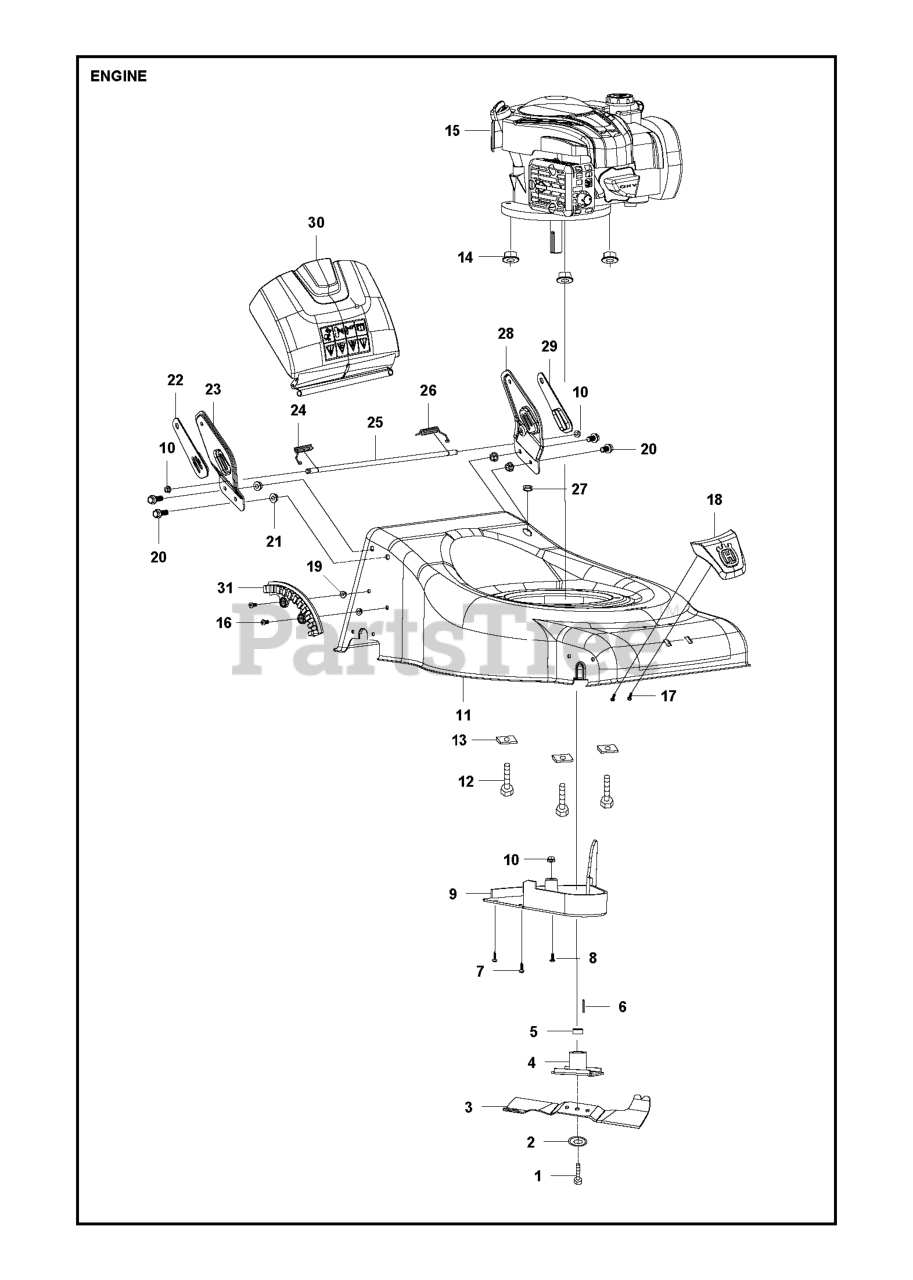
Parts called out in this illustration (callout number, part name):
8	SCREW M6*16 #26800204601
10	LOCK NUT M6,GB/T6187.1-2000 #2
14	LOCKING BOLT M8,GB6187.1 #2680
20	BOLT M8*16 #26800606401
22	PLATE RIGHT
23	BRACKET RH
24	SPRING #26801125501
26	BRACKET #26801125401
29	PLATE LEFT
31	SEGMENT #25214200102
